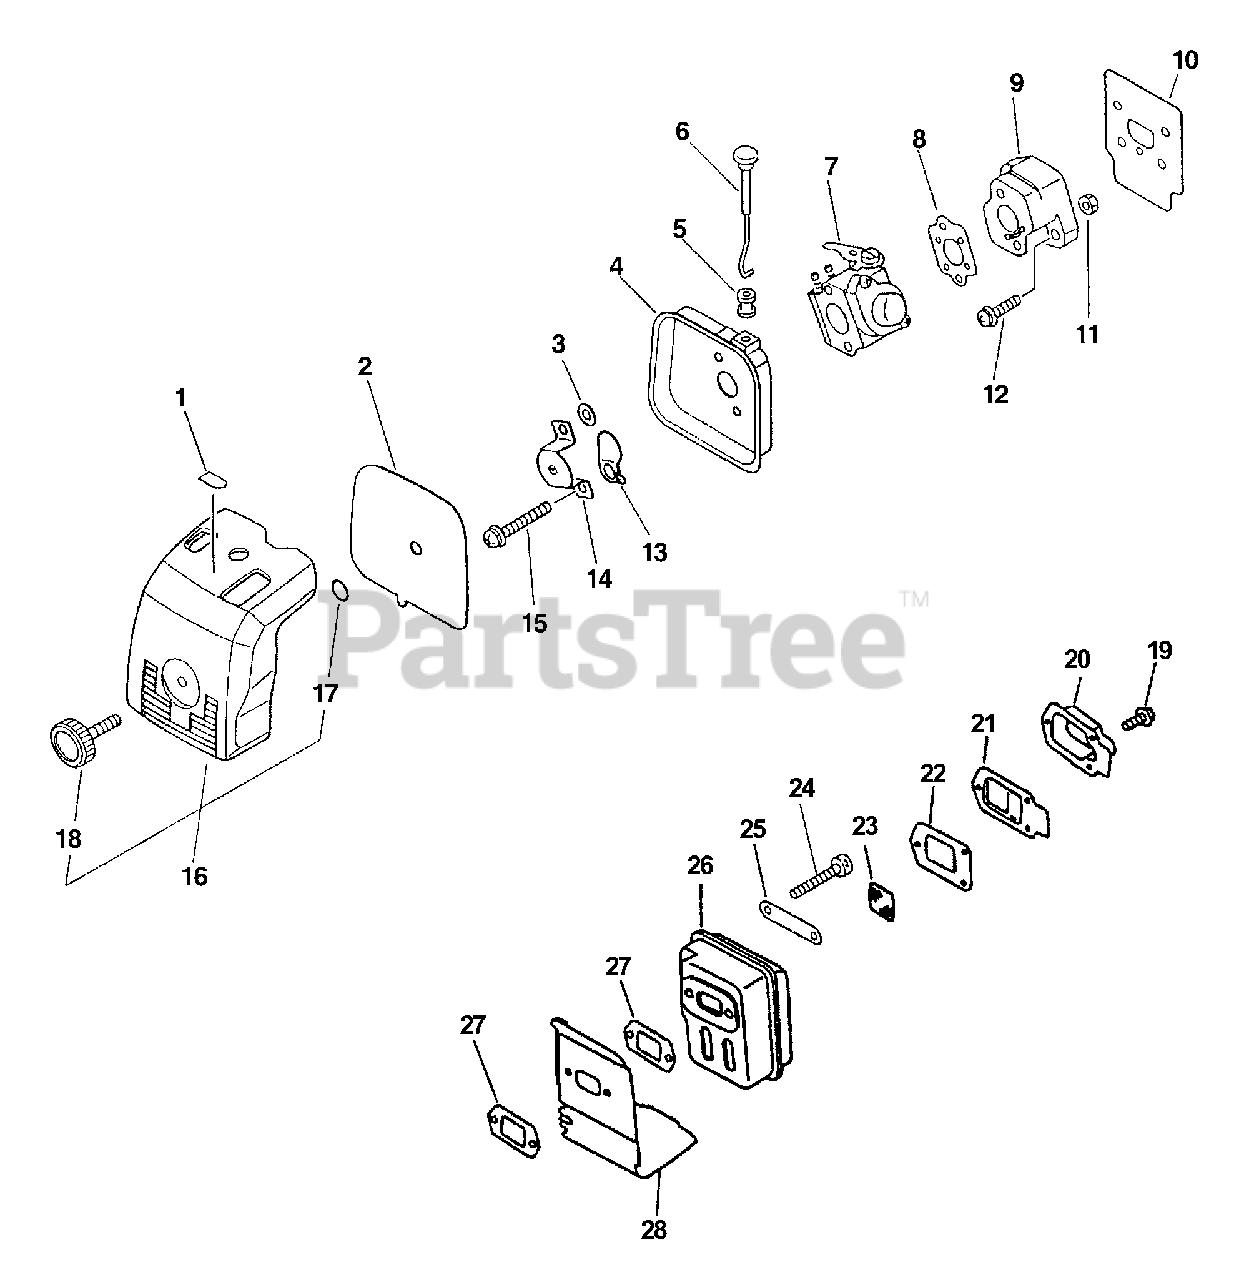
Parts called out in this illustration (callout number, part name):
1	LABEL - CHOKE
2	FILTER, AIR - HEAVY DUTY
3	WASHER - 5
4	CASE, AIR FILTER
6	ROD, CHOKE
7	CARBURETOR C1U-K23A
8	GASKET, INTAKE
9	INSULATOR, INTAKE
10	SHIELD, INTAKE
12	SCREW - 5X20
13	SHUTTER, CHOKE
14	PLATE, PREVENT
15	SCREW - 5X57
16	AIR FILTER COVER ASSY
17	O-RING - 3
18	THUMBSCREW
19	SCREW - 4X10
20	GASKET, EXHAUST - INNER
21	GUIDE, EXHAUST
22	GASKET, EXHAUST
23	SCREEN, SPARK ARRESTOR
24	SCREW - 5X55
27	GASKET, EXHAUST
28	COVER, MUFFLER
29	GASKET KIT
